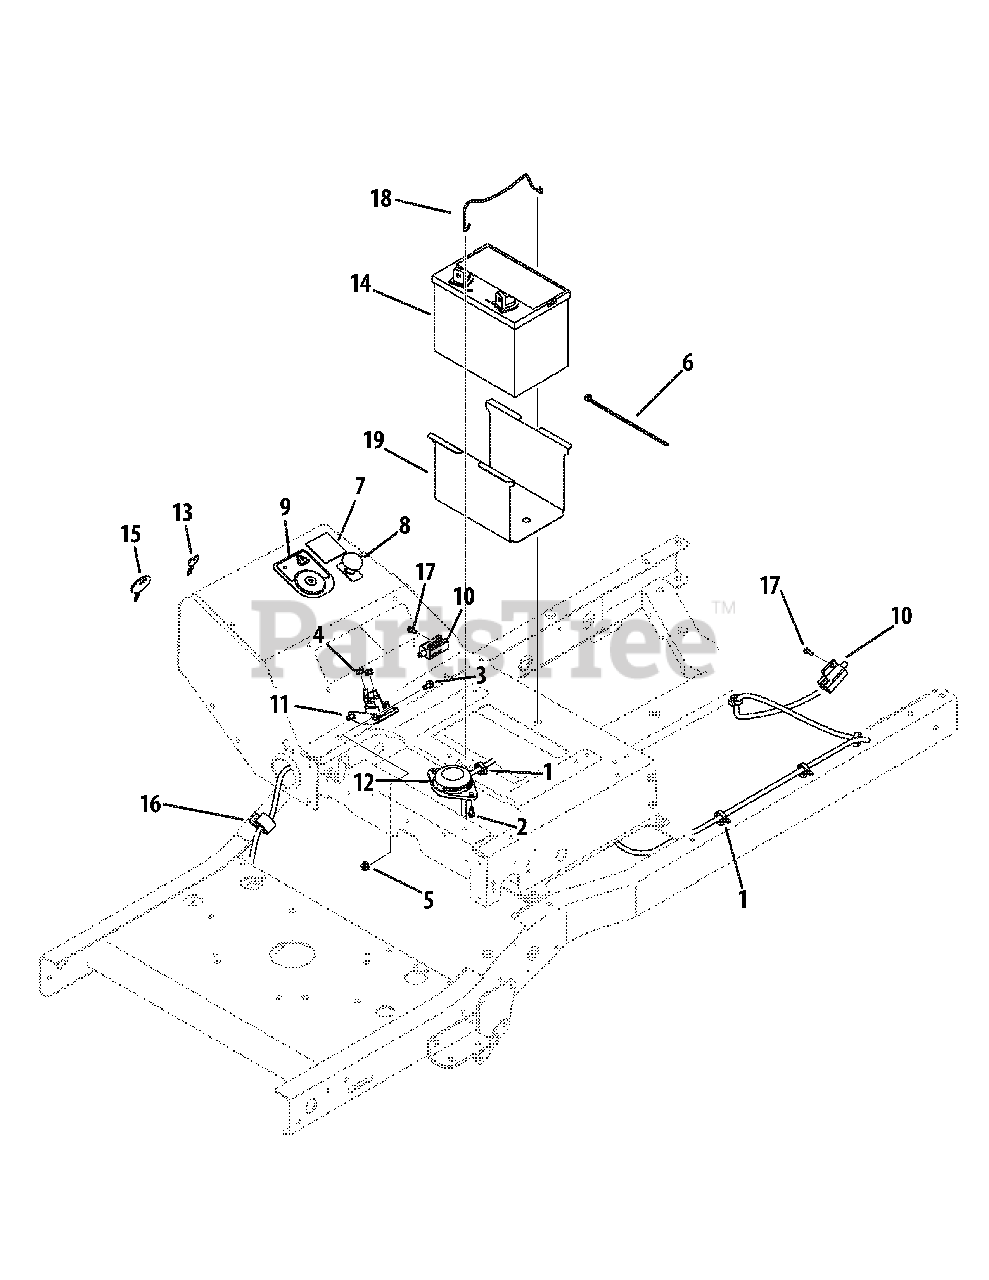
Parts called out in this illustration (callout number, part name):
1	Electrical Conduit Clip, 1/2
2	Hex Washer Screw, #12-16 x .50
3	Hex Washer Screw, 1/4-20 x 0.500
4	Sems Nut, 1/4-20
5	Flange Lock Nut, 1/4-20
6	Cable Tie, 3/16 x .05 x 7.4
7	Hour Meter/Service Minder
8	Electric PTO Switch
9	Key Switch
10	Interlock Switch
11	Solenoid
12	Seat Switch
13	Universal Key
15	Key, Yellow
16	Clamp, 1.0
17	Shoulder Screw, #10-32 x .500
18	Battery Rod
